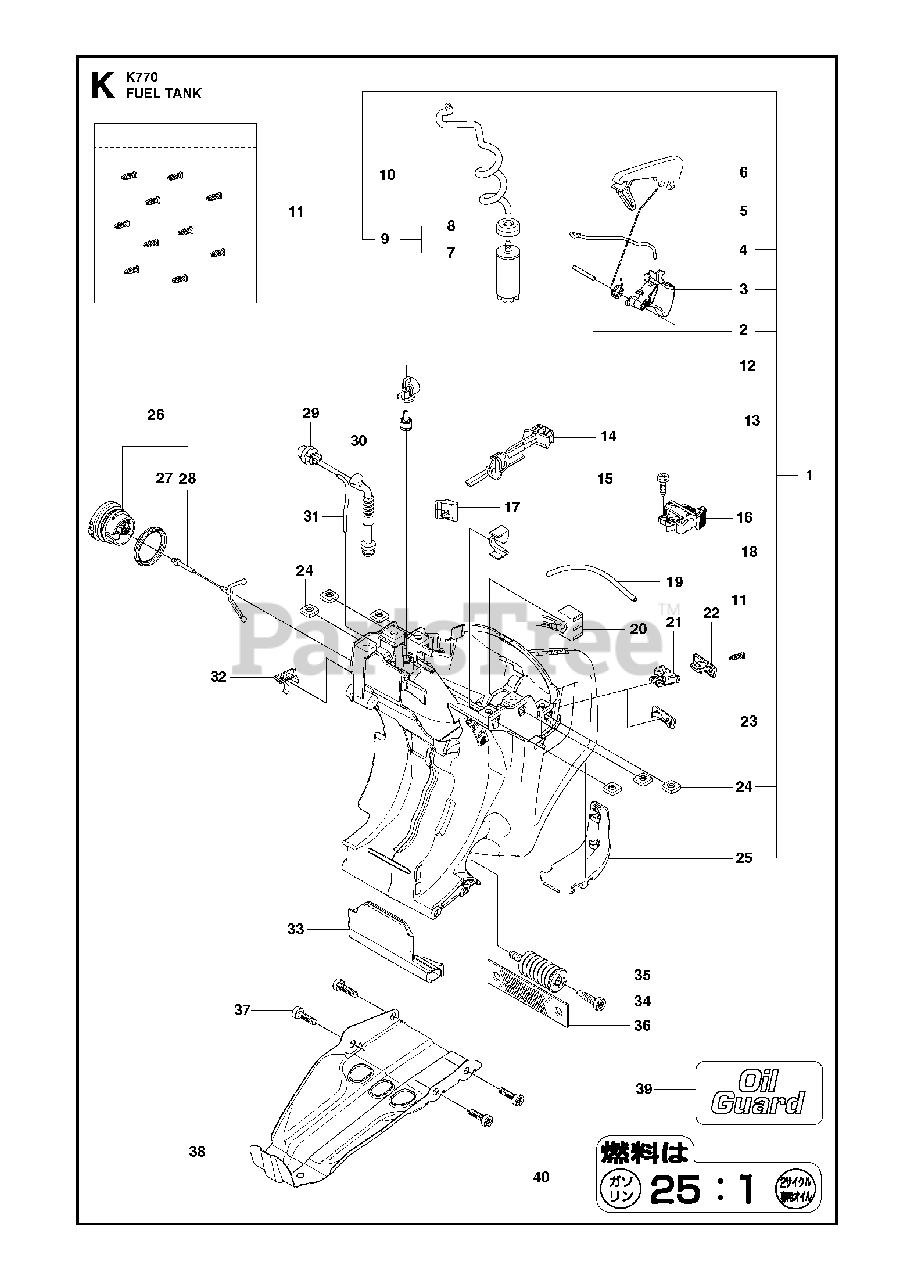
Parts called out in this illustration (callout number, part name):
1	FUEL TANK ASSYIncl. 2 - 10, 12-13, 18, 23-25
2	PARALLEL PIN
3	THROTTLE CONTROLOIL GUARD
3	THROTTLE CONTROL
4	THROTTLE ROD
6	THROTTLE LOCKOUTOIL GUARD
9	FUEL FILTERIncl. 7 - 8
10	FUEL HOSEOil Guard
11	KITOil Guard. Incl. 10 pins
12	TANK VENT VALVE ASSY
14	CHOKE CONTROL
15	SCREW CITXPANT
20	ELECTRONIC BOX
26	TANK CAP ASSY
34	SCREW ITXSCM
35	ANTIVIBRATION ELEMENT
37	SCREW ITXSCT
40	LABELJapan Only
